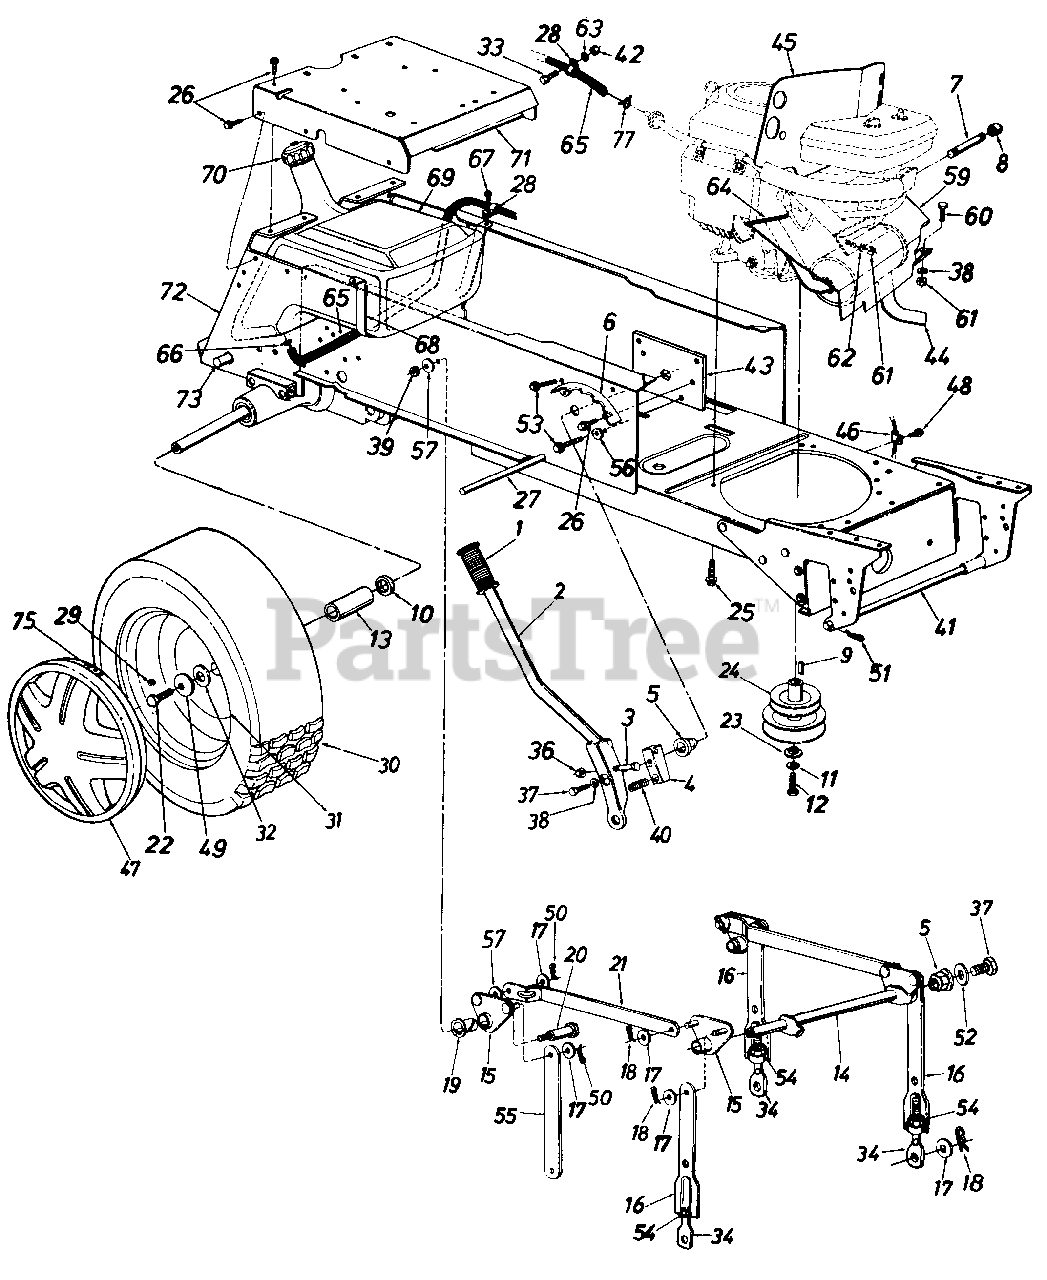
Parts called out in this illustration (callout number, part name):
1	Grip
2	Lift Handle Ass'y.
3	Hex Bolt 5/16-18 x 1.5" Lg.
4	Lift Shaft Drive
5	Plastic Hex Brg. 5/8" l.D.
8	Pipe Cap 3/8-18 Npt.
9	Sq. Key 1/4" x 1/4n x 1,50" Lg.
10	Fl-Wash. .76" l.D. x 1.49" O.D.
11	L-Wash. 7/16" l.D.
12	Hex Scr. 7/16-20 x 1.50" Lg.
13	Sleeve .75" l.D. x 1.0" O.D.
14	Lift Shaft Ass'y.
15	Lift Pivot Brkt. Ass'y.
17	Fl-Wash. 1/2" l.D. x 1.00n O.D. x ,ogon
18	Hairpin Cotter
19	Nyliner 5/8" l.D. x .88" Lg.
20	Shld. Bolt .618" Dia. x .96" Lg. 3/8-16
23	Flat Wash. .44" I.D. x 1.25" O.D. x .17"
24	Two-Step Engine Pulley 5.56 & 3.5
25	Hex Wash. Hd. Scr. 3/8-16 x 1.25n Lg.
26	Hex Thd. Rolling Scr. 5/16-18 x.75" Lg.
27	Running Board Rod
29	Air Valve
32	Flat Washer ,34n l.D.
33	Hex Bolt 1/4-20 x .62n Lg.
34	Eye Bolt Adj. Link 1/2-13 Thd.
36	Hex Cent. L-Nut 5/16-18 Thd.
37	Hex Bolt 5/16-24 x .62n Lg.
38	L-Wash. 5/16n l.D.
39	Hex Top L-Nut 3/8-16 Thd.
40	Compression Spring
41	Deck Connecting Rod
42	Hex Nut 1/4-20 Thd.
45	Heat Shield
46	Mounting Clamp
47	Hubcap
48	Hex Wash. Hd. TT-Tap Scr. 1/4-20 x .5n Lg.
49	Bell-Wash..39" l.D.
50	Cotter Pin .09 Dia. x 1.0" Lg.
51	Int. Cotter Pin
52	Flat Wash. .34" l.D. x 1.12" O.D. x .125"
53	Hex Wash. Hd. AB-Tap Scr. 5/16-24 x .5" Lg.
54	Hex Nut 1/2-13 Thd .
56	Fl-Wash. .344n l.D.
57	Bell-Wash. .4n l.D. x 1.13n O.D.
59	Front Heat Shield
60	Hex Bolt 5/16-18 x .75n Lg.
61	Hex Nut 5/16-18 Thd.
62	L-Wash. 5/16n l.D.
63	L-Wash. 1/4n l.D.
64	Trim Strip 12n Lg.
65	Fuel Line 50n Lg.
66	Hose Clamp
67	Hex AB-Tap Scr. 1/4 x .62" Lg.
68	Fuel Tank Strap
69	Gas Tank
71	Seat Plate
75	Spring Clip
